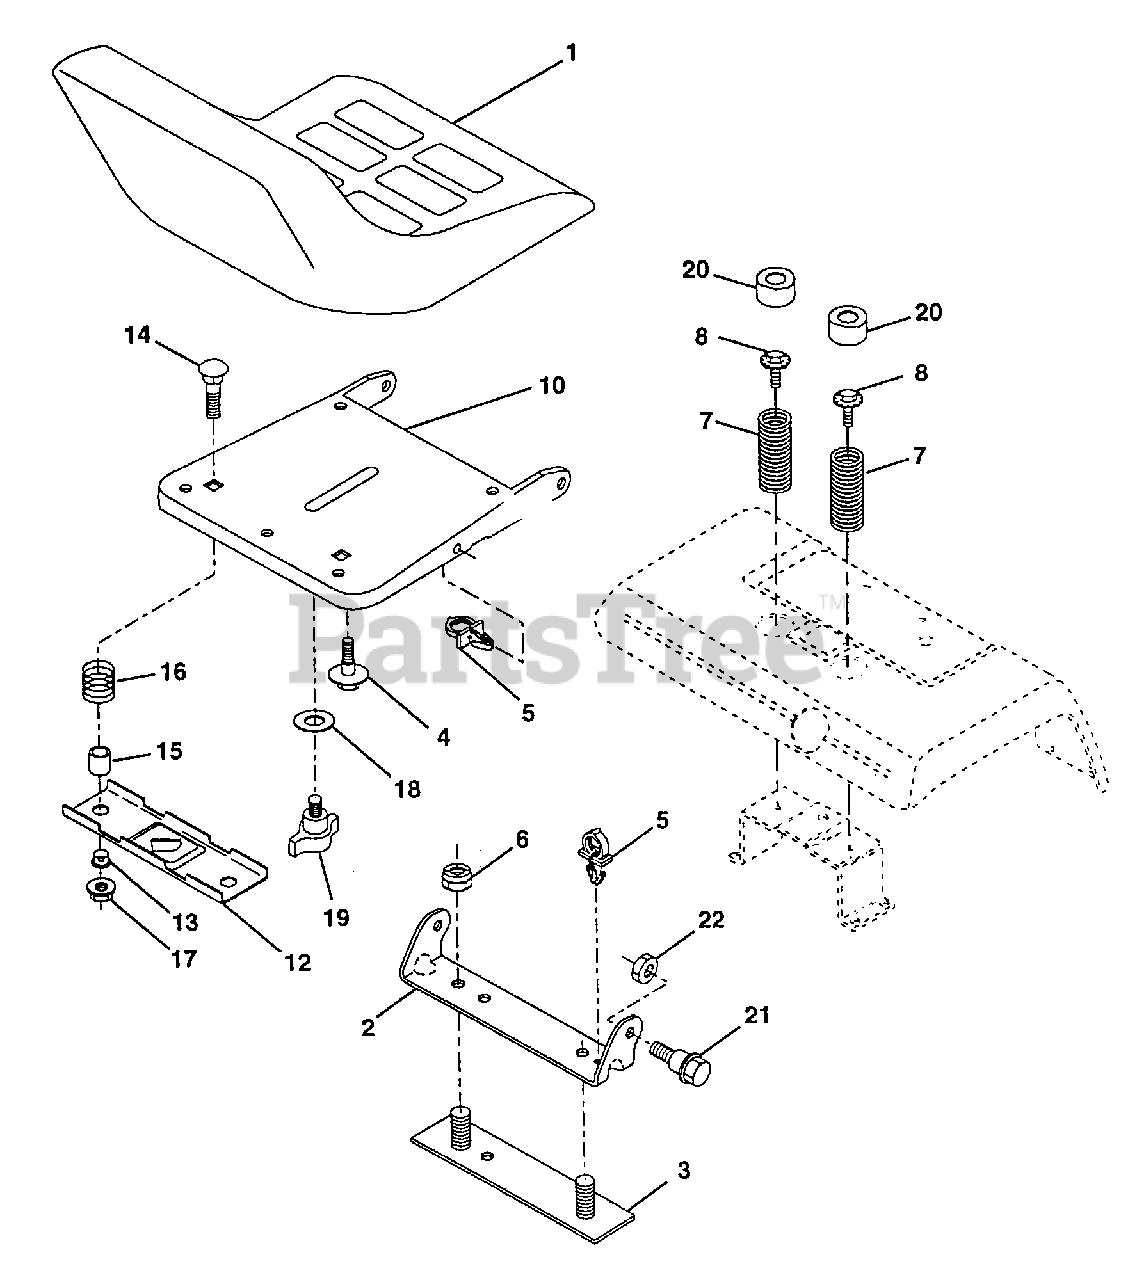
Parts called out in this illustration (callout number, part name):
1	Seat
2	Bracket, Pivot Seat
3	Strap, Fender
4	Bolt, Shoulder 5/16-38 X.62
5	Clip, Push In Hinged
6	Nut, Crownlock 3/8-16 Unc
7	Spring, Seat Cprsn
8	Bolt 5/16-18 UNC X 3/4
10	Pan, Seat (AYP part number)
12	Bracket, Mounting Switch
13	Bushing, Snap
14	Bolt, Carriage 1/4-20 X 1-1/2
15	Spacer, Split
16	Spring, Cprsn
17	Nut, Lock 1/4 Lge Flg Gr. 5 (AYP part number)
18	Washer 17/32 X 1-3/16 X 12 Ga.
19	Knob, Seat
20	Cap, Spring Seat
21	Bolt, Shoulder 5/16-18 Unc (AYP part number)
22	Nut, Crownlock 5/16-18 Unc
